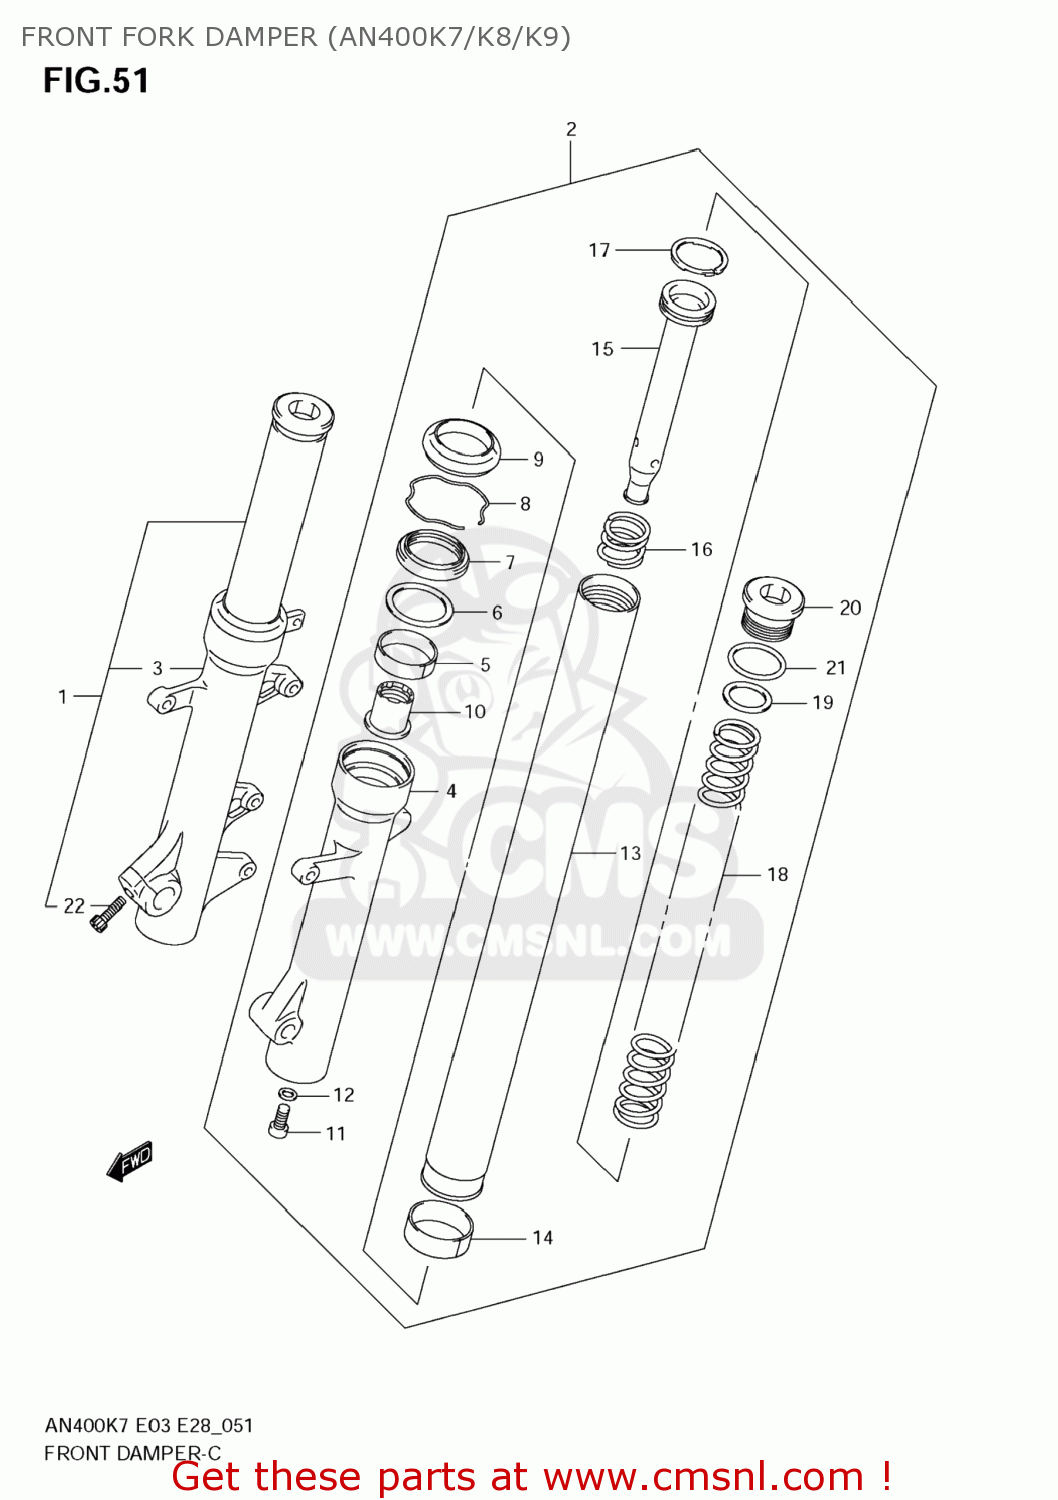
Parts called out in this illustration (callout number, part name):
1	DAMPER ASSY,FR FORK,R
2	DAMPER ASSY,FR FORK,L
3	TUBE,OUTER,R
4	TUBE,OUTER,L
5	METAL,SLIDE
6	WASHER,FORK OIL SEAL
7	SEAL,OIL
8	RING,OIL SEAL STOPPER
9	SEAL,DUST
10	PIECE,OIL LOCK
11	BOLT
12	GASKET (NAS)
13	TUBE,INNER
14	PISTON
15	CYLINDER
16	SPRING,REBOUND
17	RING,PISTON
18	SPRING,FR
19	WASHER,STEM HEAD(24.5X34X1.6)
20	CAP
21	O RING(D:3.5,ID:31.7)
22	BOLT
